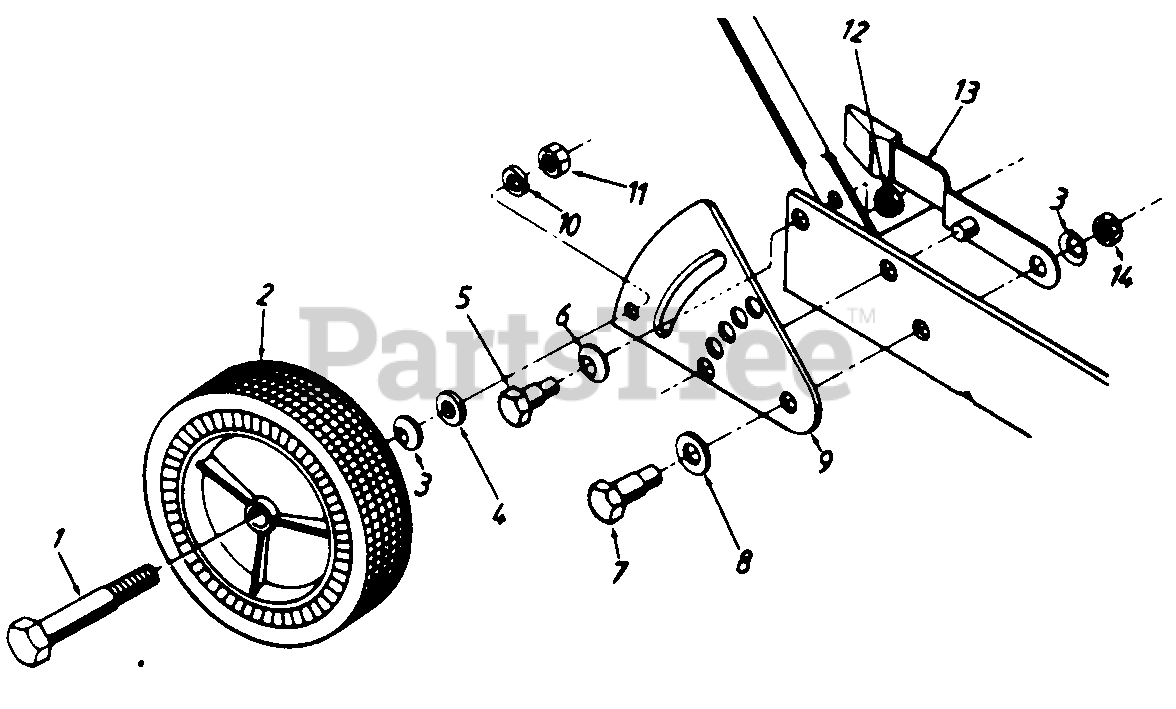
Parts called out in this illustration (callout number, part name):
1	Shld. Bolt .498" Dia. x 1.45"
2	Rear Wheel
3	Bell-Wash. .40" I.D. x .88" OD.
4	Fl-Wash. .39" I.D. x 1.12"
5	Shld. Bolt .50" Dia. x .25" Lg.
6	Bell-Wash. .515" I.D. x 1.14" 0.D.
7	Shld. Bolt .50" Dia. x .215" Lg.
8	Fl-Wash. .51" I.D. x 1" OD.
11	Hex Nut 3/8-16 Thd.
12	Hex L-Nut 3/8-16 Thd.
13	Spring Adj. Lever
14	Hex Jam Nut 3/8-16 Thd.
